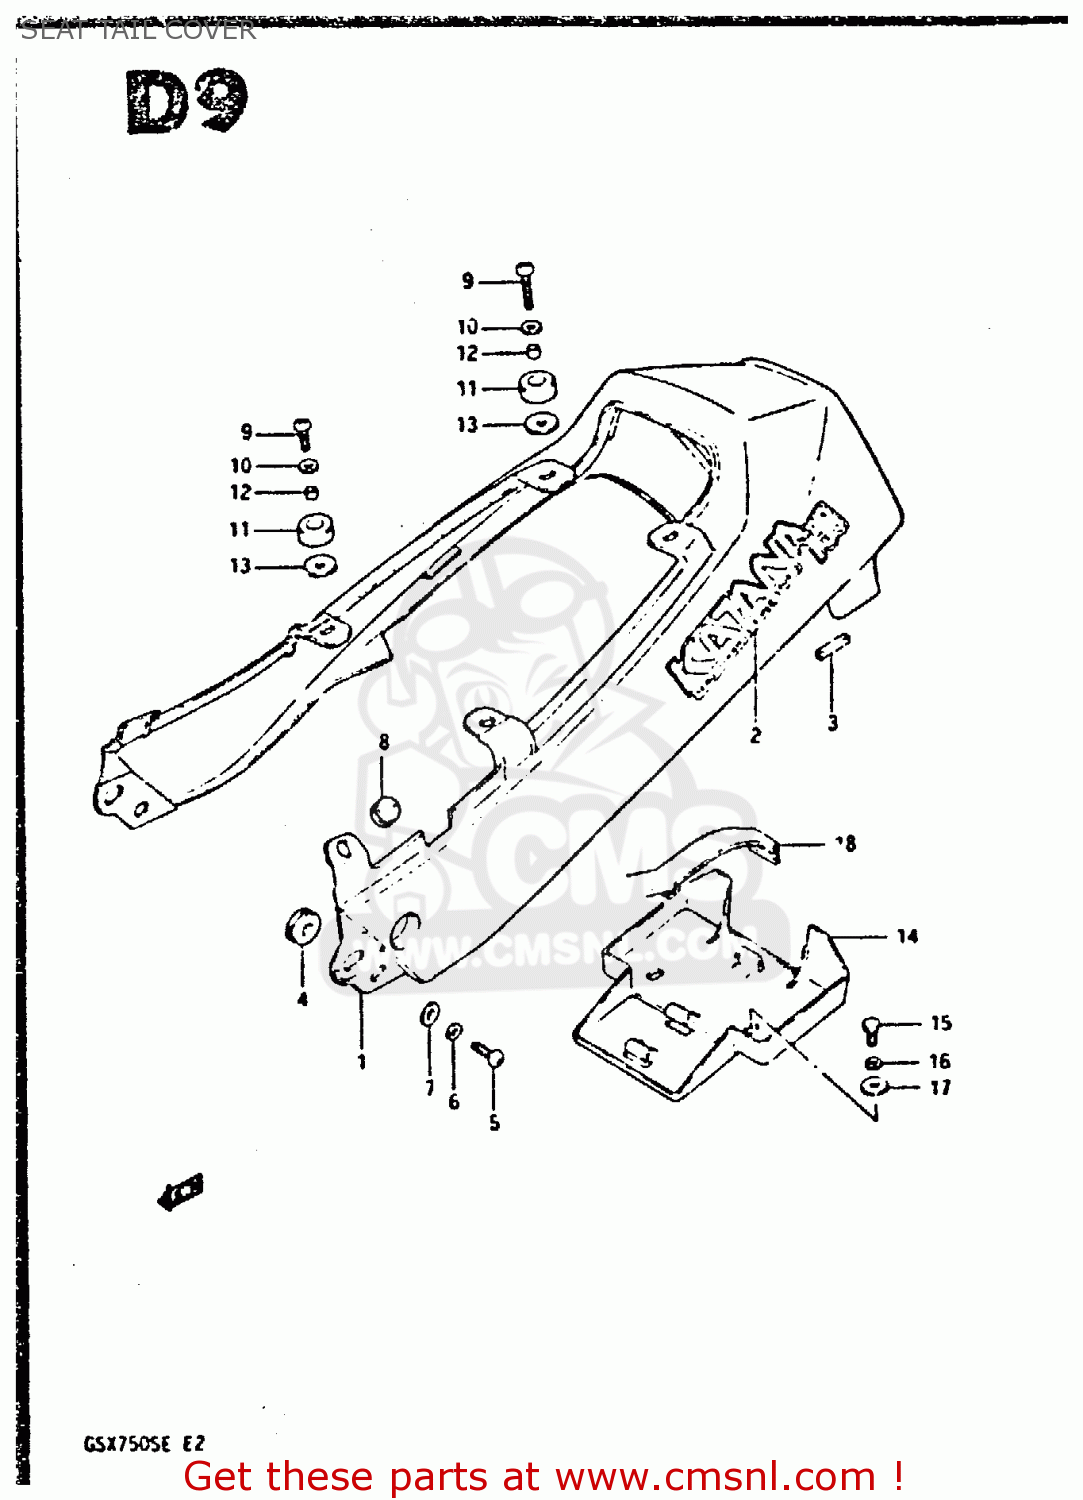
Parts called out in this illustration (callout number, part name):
1	TAIL COVER, SEAT (WHITE)
2	EMBLEM
3	CUSHION
4	CUSHION
5	SCREW
6	WASHER,LOCK
7	WASHER
8	CUSHION,FRAME COVER,R UPR
9	SCREW
10	WASHER, LOWER
11	CUSHION,COVER
12	SPACER
13	WASHER (6.5X24X1.6)
14	FLAP SET, SEAT TAIL COVER
15	BOLT 6X16
16	WASHER,LOCK
17	WASHER,LOCK
18	BAND
